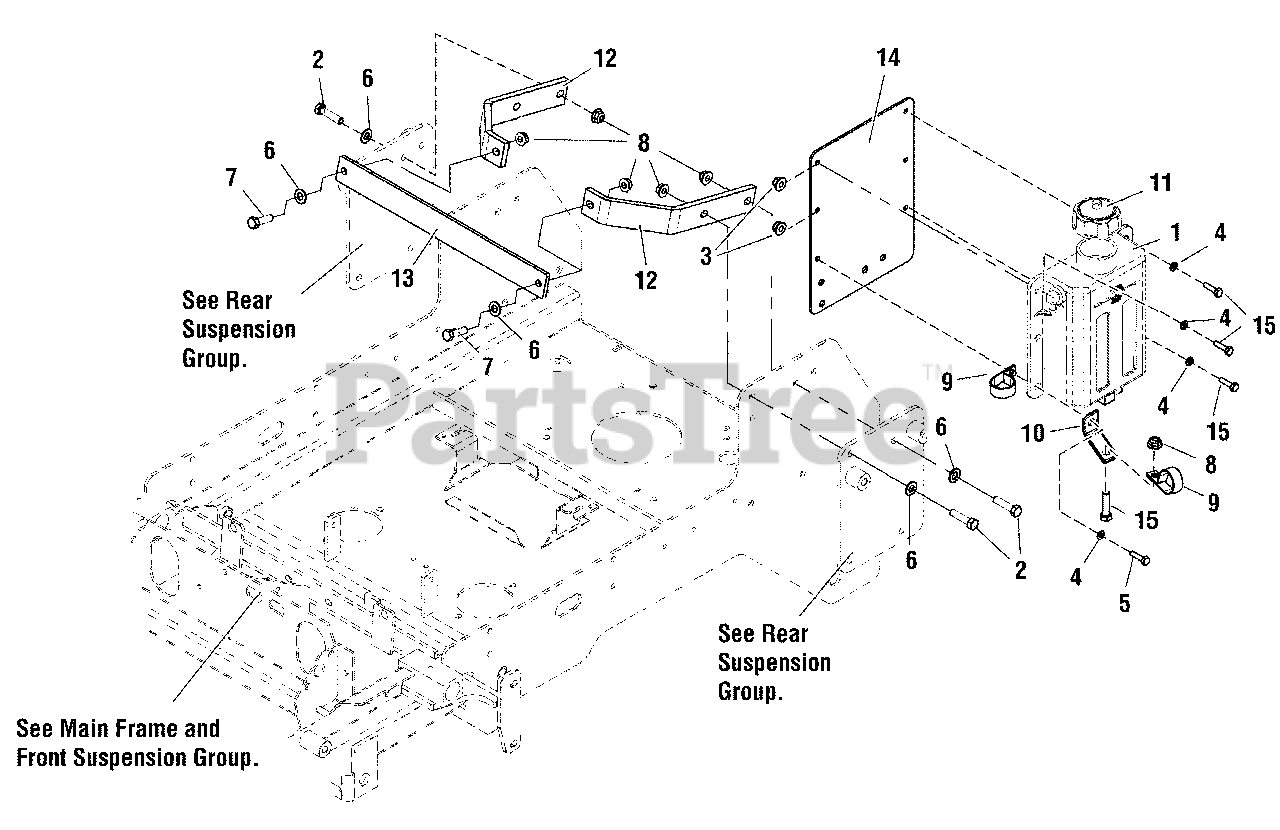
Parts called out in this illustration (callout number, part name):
1	TANK, HYDRAULIC, ASSEMBLY (See Hydraulic Group)
2	BOLT, 3/8-16 X 1-1/2" GD5 YZ
3	NUT, 1/4-20 HEX NYLOCK FLANGE (5025391)
4	WASHER, 1/4 SAE (5025154)
5	BOLT, 1/4-20 X 1" GD5 CZ
6	WASHER, 3/8 SAE
7	BOLT, 3/8-16 X 1-1/4" GD5
8	NUT, 3/8-16 HEX NYLOCK FLANGE
9	CLAMP, VINYL INSULATED
10	BRACKET, HOSE - BLK
11	CAP, HYDRAULIC (See Hydraulic Group)
12	BAR, STABILIZER, SIDE
13	BAR, STABILIZER, CENTER - BLK
14	PLATE, HYDRAULIC TANK MOUNT
15	BOLT, 1/4-20 X 3/4" G
